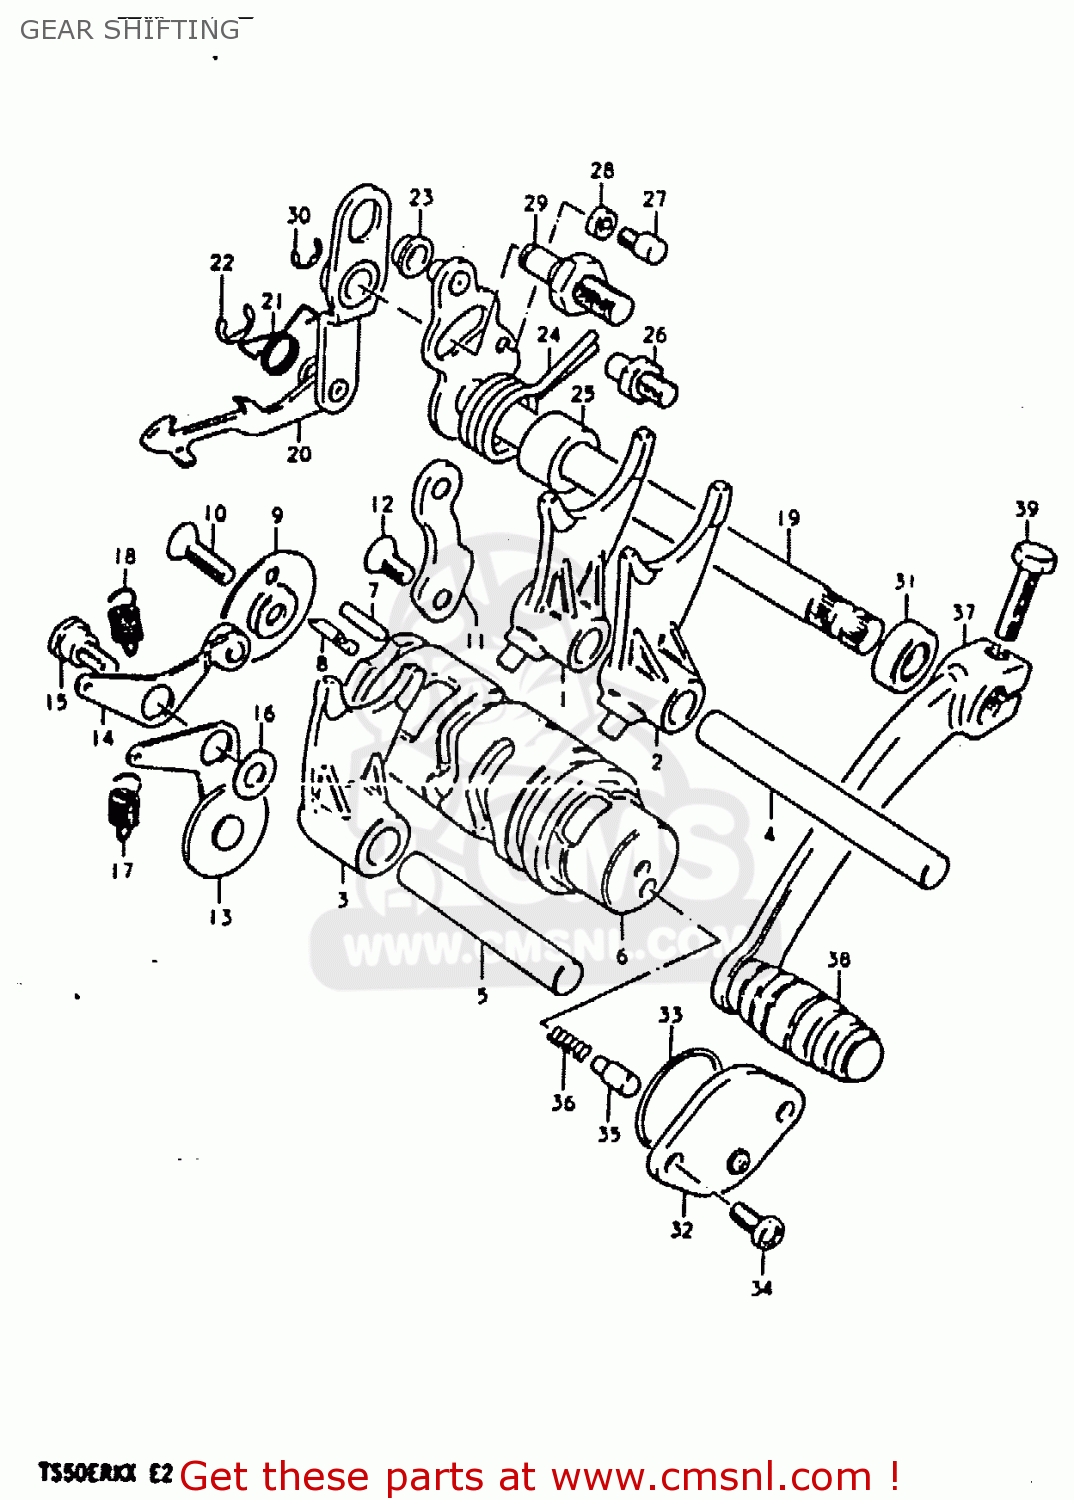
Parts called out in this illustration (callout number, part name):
1	FORK,GEAR SHIFT NO.1
2	FORK,GEAR SHIFT NO.2
3	FORK,GEAR SHIFT NO.2
4	SHAFT,GEAR SHIFT FORK
5	SHAFT,GEAR SHIFT FORK
6	CAM,GEAR SHIFT
7	PIN(4X15.8)
8	PIN
9	RETAINER,GEAR SHIFT CAM DR PIN
10	SCREW
11	GUIDE,GEAR SHIFT CAM
12	SCREW
13	STOPPER,GEAR SHIFT CAM
14	STOPPER,GEAR SHIFT CAM NEUTRAL
15	BOLT(6X18.3)
16	WASHER
17	SPRING
18	SPRING
19	SHAFT,GEAR SHIFT
20	PAWL,GEAR SHIFTING
21	SPRING
22	E RING
23	SPACER(7X10X5)
24	SPRING
25	SPACER(12X20X15.3)
26	STOPPER,GEAR SHIFT CAM
27	BOLT,GEAR SHAFT RETURN SPR SET
28	NUT 6MM
29	STOPPER,GEAR SHIFT CAM
30	E RING 6MM
31	OIL SEAL
32	BODY,GEAR SHIFT SWITCH
33	O-RING (D:2.4 ID:26.2)
34	SCREW
35	PIN(5X15.5)
36	SPRING
37	LEVER ASSEMBLY,GEAR SHIFTING
38	RUBBER,GEAR SHIFT PEDAL
39	BOLT
